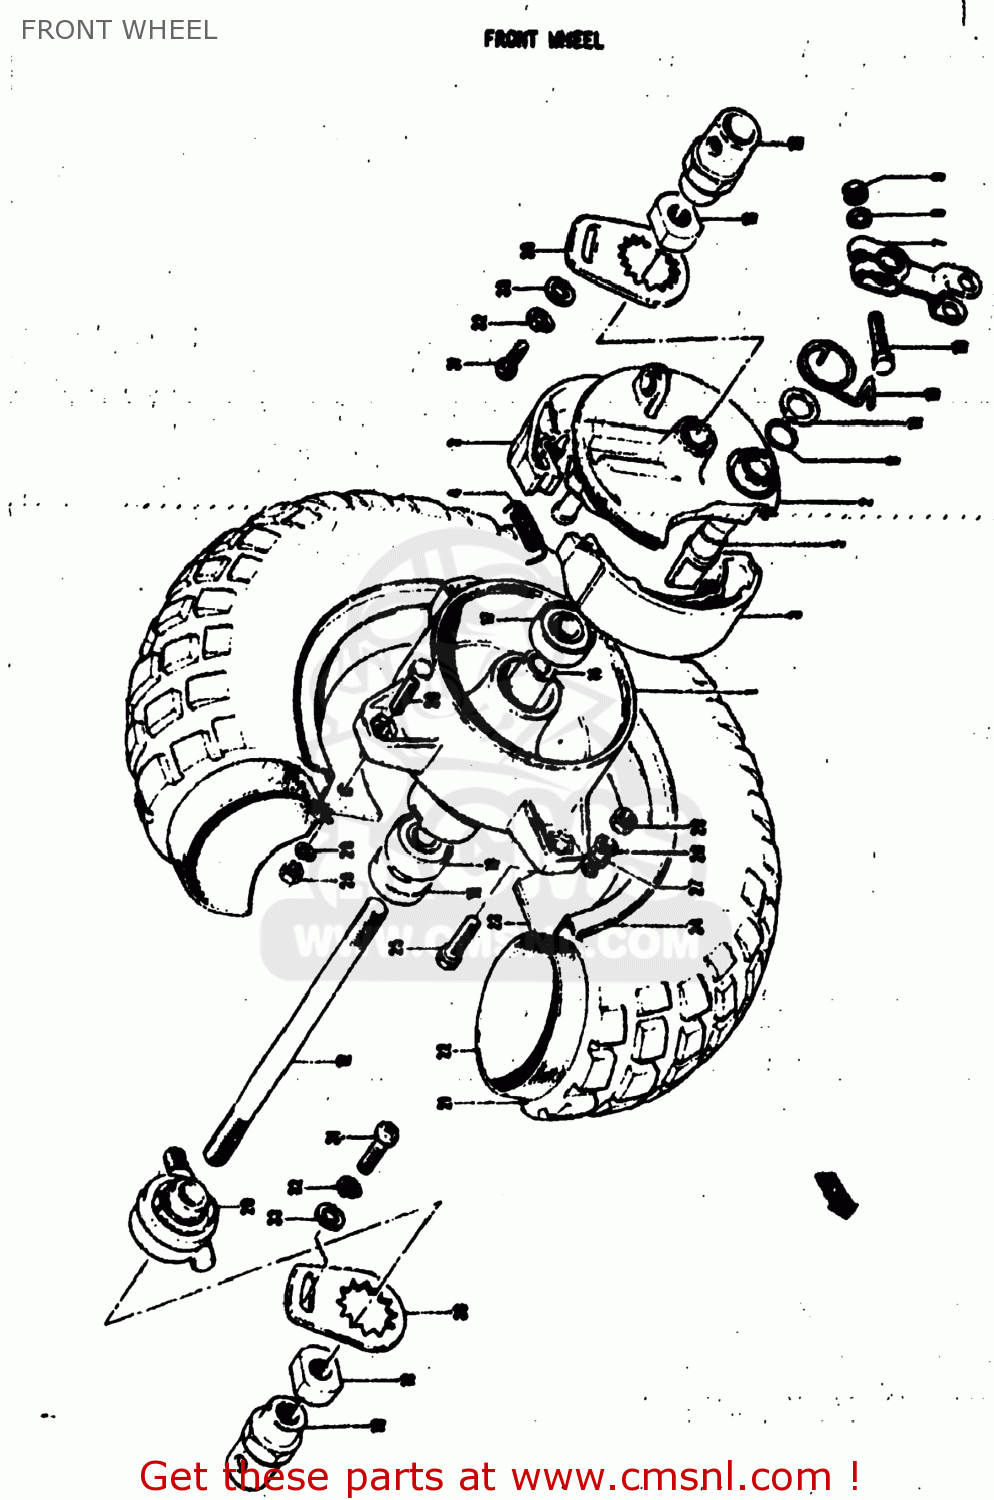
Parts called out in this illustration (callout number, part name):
3	SHOE,BRAKE
4	SPRING(L:34)
5	CAM,FRONT BRAKE
6	O RING(D:2.5,ID:11.4)
7	LEVER,REAR BRAKE CAM
8	WASHER
9	NUT
10	BOLT
11	WASHER(12.5X20X1)
16	BEARING
17	BEARING
18	NUT,FRONT AXLE
19	SPRING
22	TUBE ASSY,WHL I
25	BOLT
26	HEXAGON BOLT
27	WASHER
28	LOCK WASHER
29	NUT
31	SCREW(5X12)
32	LOCK WASHER
33	WASHER (5.5X16X1.2)
